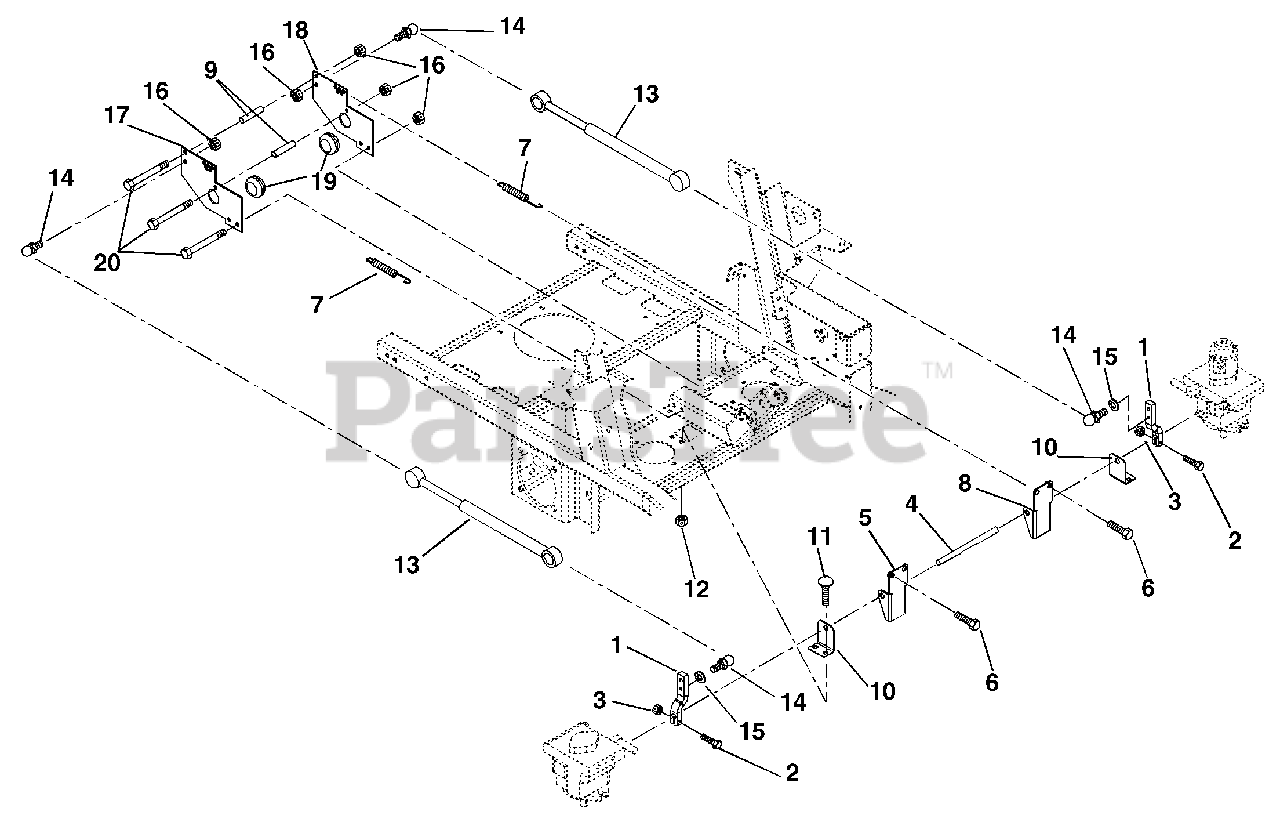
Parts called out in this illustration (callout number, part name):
1	Arm-Pump Actuating
2	Bolt-Hex .25-20 x 1.25 Grade 5
3	Nut-Locking-Center .25-20
4	Rod-Pivot
5	Pivot-Neutral Right-Hand
6	Bolt-Hex .31-18 x 1.00 Grade 5
7	Spring-Tension .085 x .60 x 5.13
8	Pivot-Neutral Left-Hand
10	Support-Pivot Rod
11	Bolt-Round Head Square Neck .31-18 x .75
12	Nut-Locking-Nylon .312-18
13	Dampener Control
14	Stud-Ball
15	Washer-Locking .31 x .078
16	Nut-Locking-Center .31-18
17	Anchor, Damper (020, 029, 030, 034 ,035)
18	Anchor, Damper (020, 029, 030, 034 ,035)
18	Anchor, Damper (032, 033)
19	Grommet .125 x 1.000
20	Bolt-Hex .31-18 x 2.50 Grade 5
